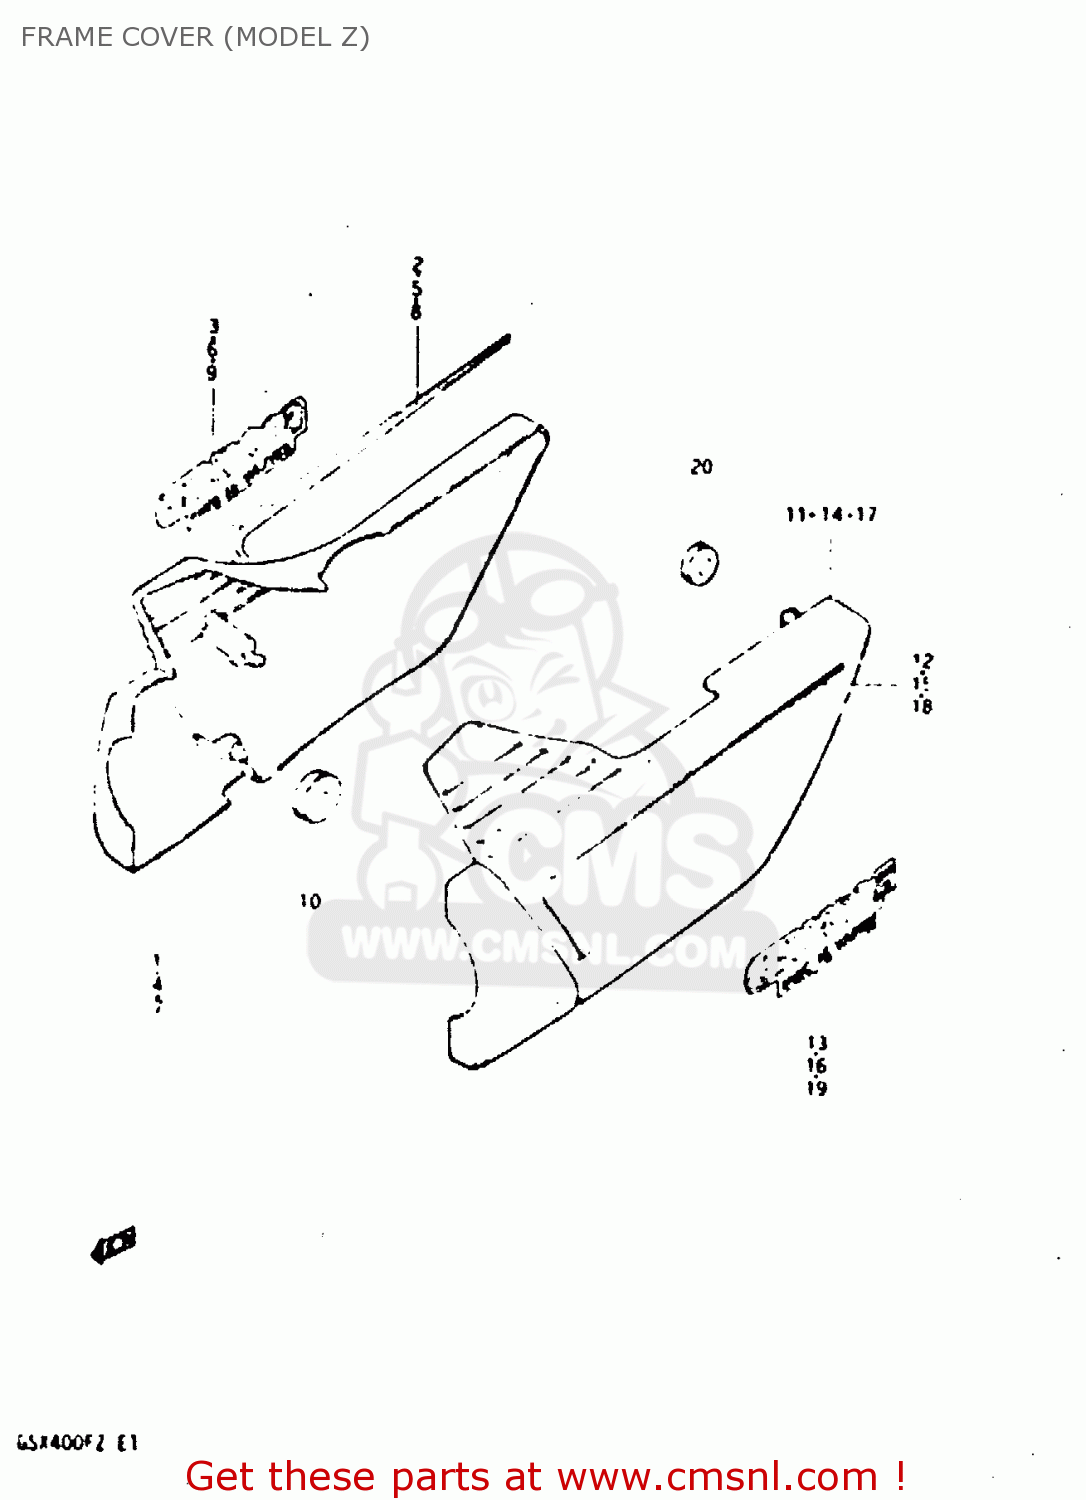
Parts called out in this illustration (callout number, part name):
1	COVER, FRAME RH (BLUE)
2	TAPE, RH
3	EMBLEM, RH
4	COVER, FRAME RH (SILVER)
5	TAPE, RH
6	EMBLEM, RH
7	COVER, FRAME RH (RED)
8	TAPE, RH
9	EMBLEM, RH
10	CUSHION
11	COVER, FRAME LH (BLUE)
12	TAPE, LH
13	EMBLEM, LH
14	COVER,FRAME LH
15	TAPE, LH
16	EMBLEM, LH
17	COVER,FRAME LH
18	TAPE, LH
19	EMBLEM, LH
20	CUSHION
